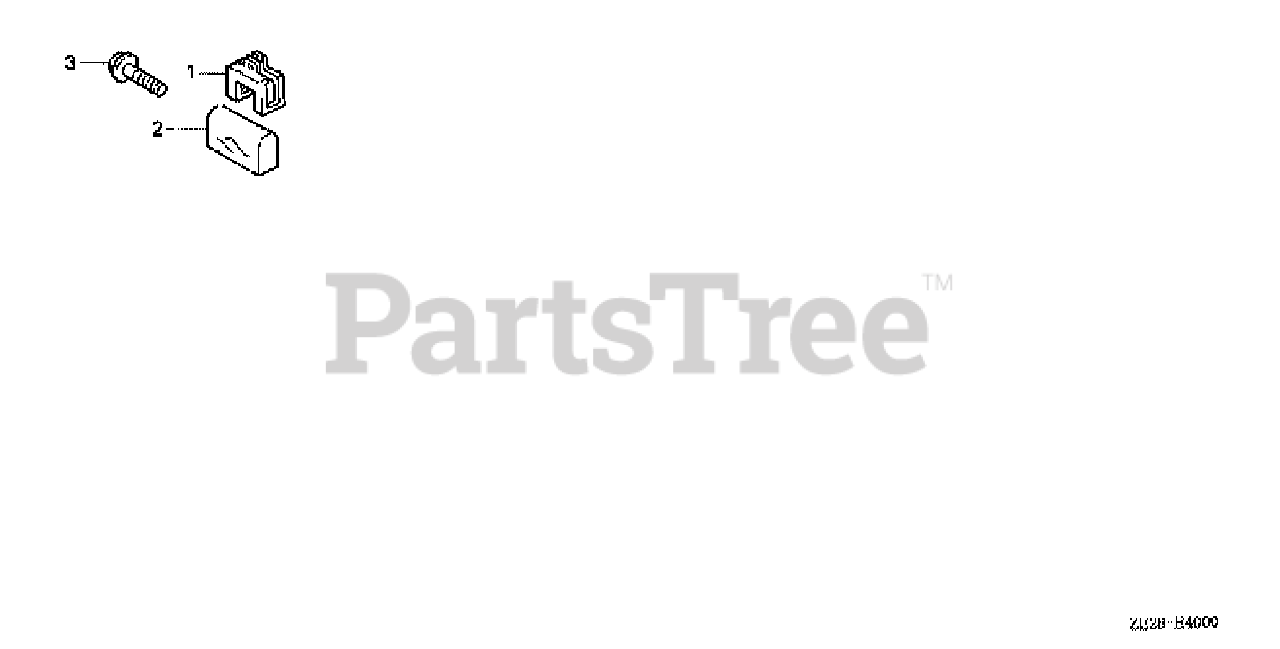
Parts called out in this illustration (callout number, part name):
1	CLIP, WIRE
2	TUBE, WIRE
3	BOLT, FLANGE (8X20)
